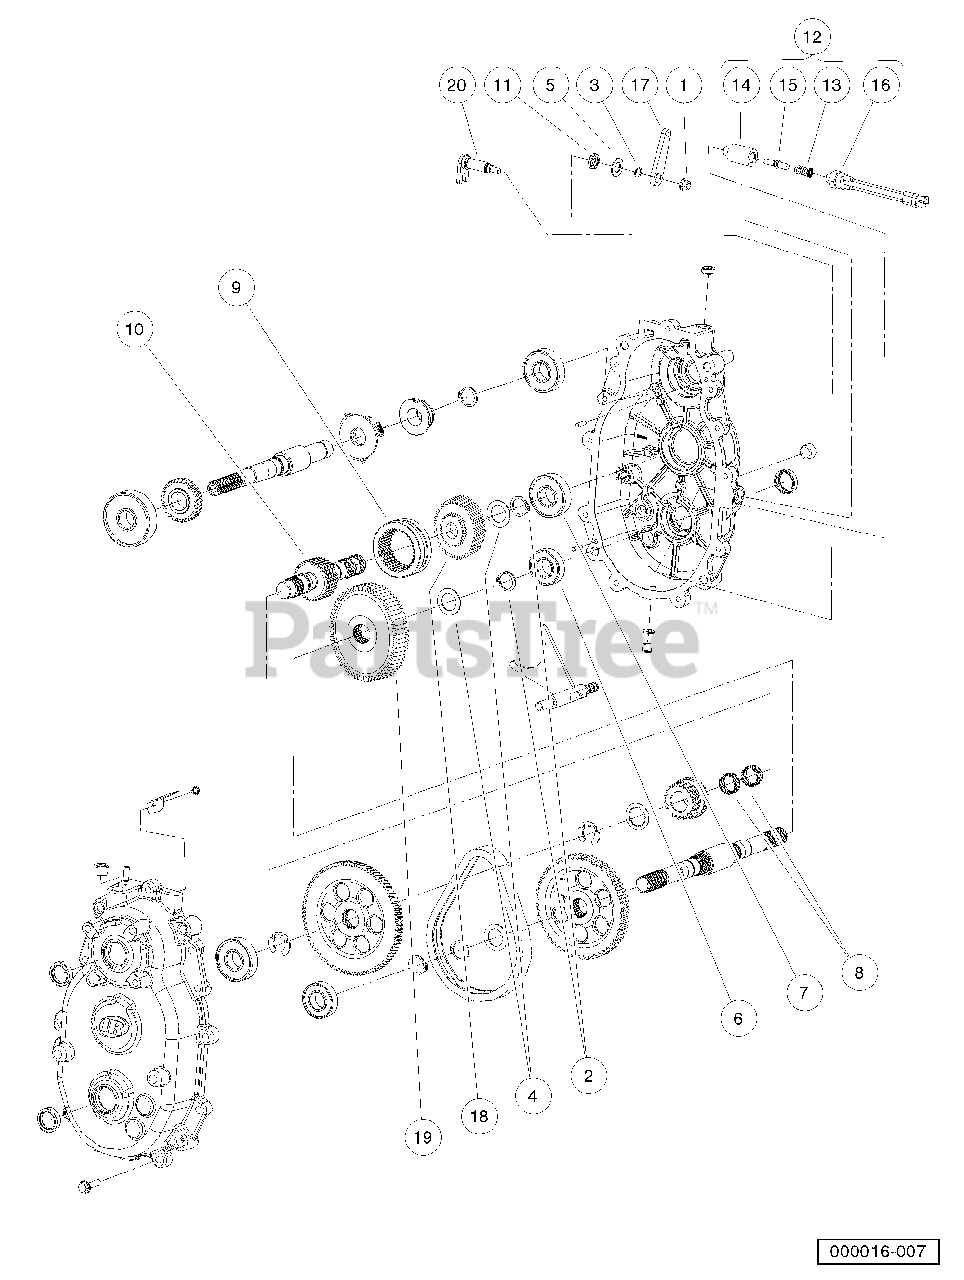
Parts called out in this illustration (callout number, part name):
1	Nut, Lock Hex, Nylon, 5/16-24
2	Ring, Retaining, Basic External
3	Ring, Retaining, External 9/16
4	Washer, Thrust, 1.007 X .062
5	Washer, Flat, .58 X 1.08 X .05
6	Bearing, Ball
7	Bearing, Ball
8	Bearing, Needle
9	Dog, Engagement
10	Shaft, Intermediate
12	Kit, Neutral Switch Repair
14	Guide, Detent Bullet
15	Bullet, Detent
16	Switch, Indicator, Pollak
17	Bellcrank, Alum
18	Gear, 35t, Spur
19	Gear, 65t Spur
20	Shaft, Shift
